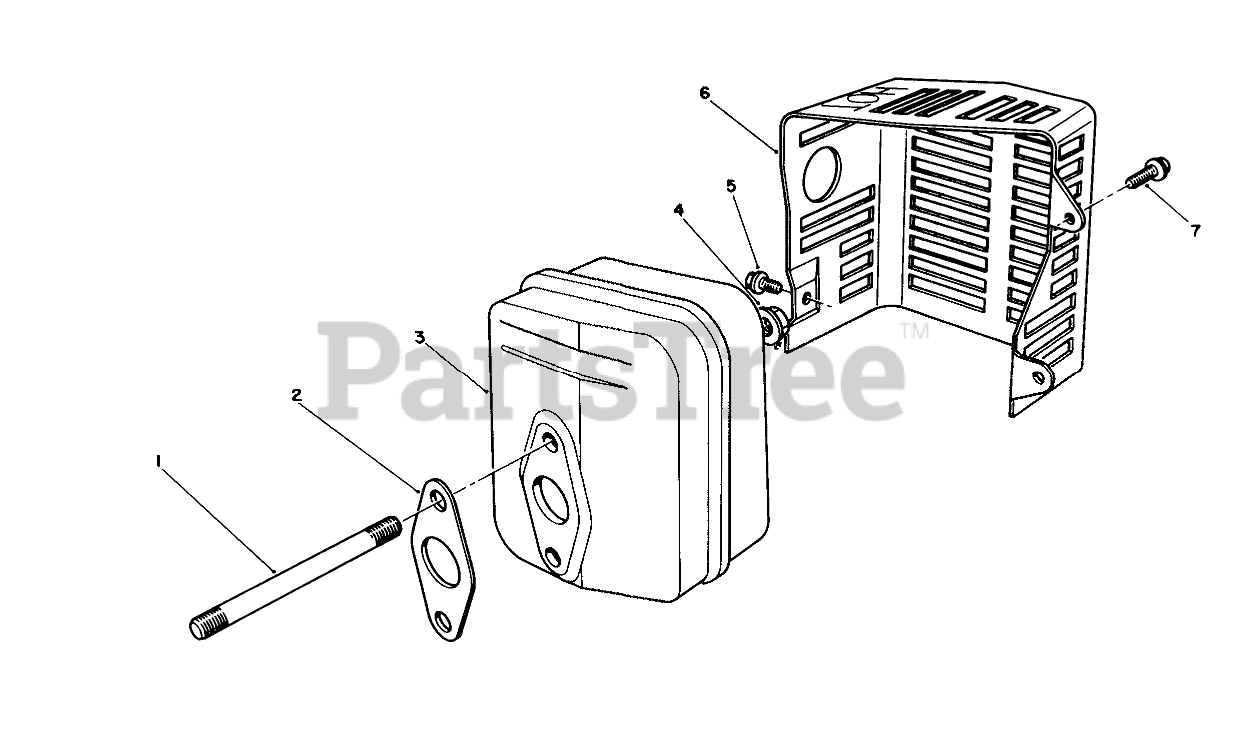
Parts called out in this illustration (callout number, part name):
2	GASKET
3	MUFFLER
5	SCREW
6	COVER
